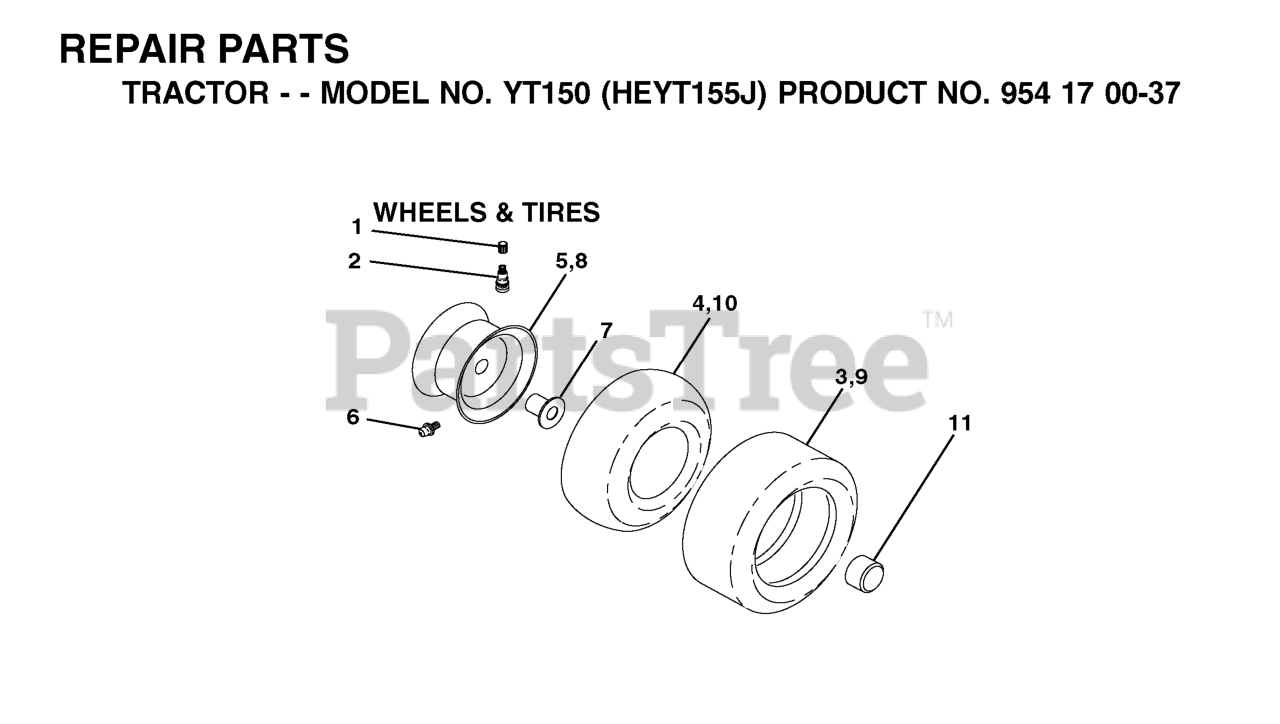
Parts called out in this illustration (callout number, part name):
2	VALVE STEM LT
3	TIRE HEAVY DUTY
4	TUBE.5.3/4.5/6
5	RIM ASM 6" FRONT SILVER
6	FITTING LT
7	BEARING T
8	RIM ASM 8" REAR SILVER
9	TIRE.TS.20X10-8
10	TUBE
11	CAP, AXLE BLK
